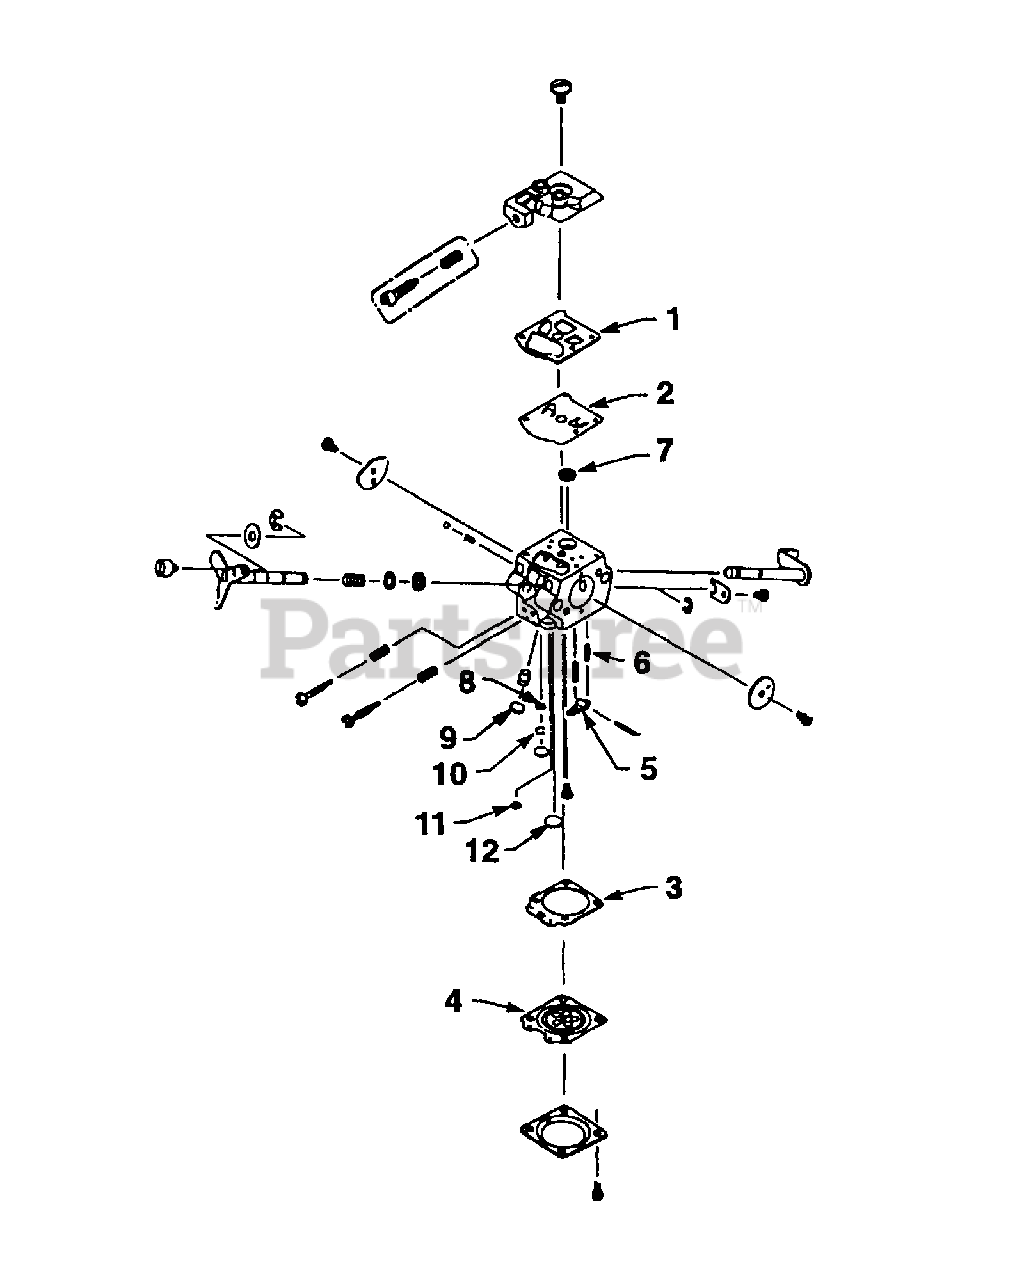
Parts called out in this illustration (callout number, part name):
1	REPAIR KIT
2	REPAIR KIT
3	REPAIR KIT
4	REPAIR KIT
5	REPAIR KIT
6	REPAIR KIT
7	REPAIR KIT
8	REPAIR KIT
9	REPAIR KIT
10	REPAIR KIT
11	REPAIR KIT
12	REPAIR KIT
